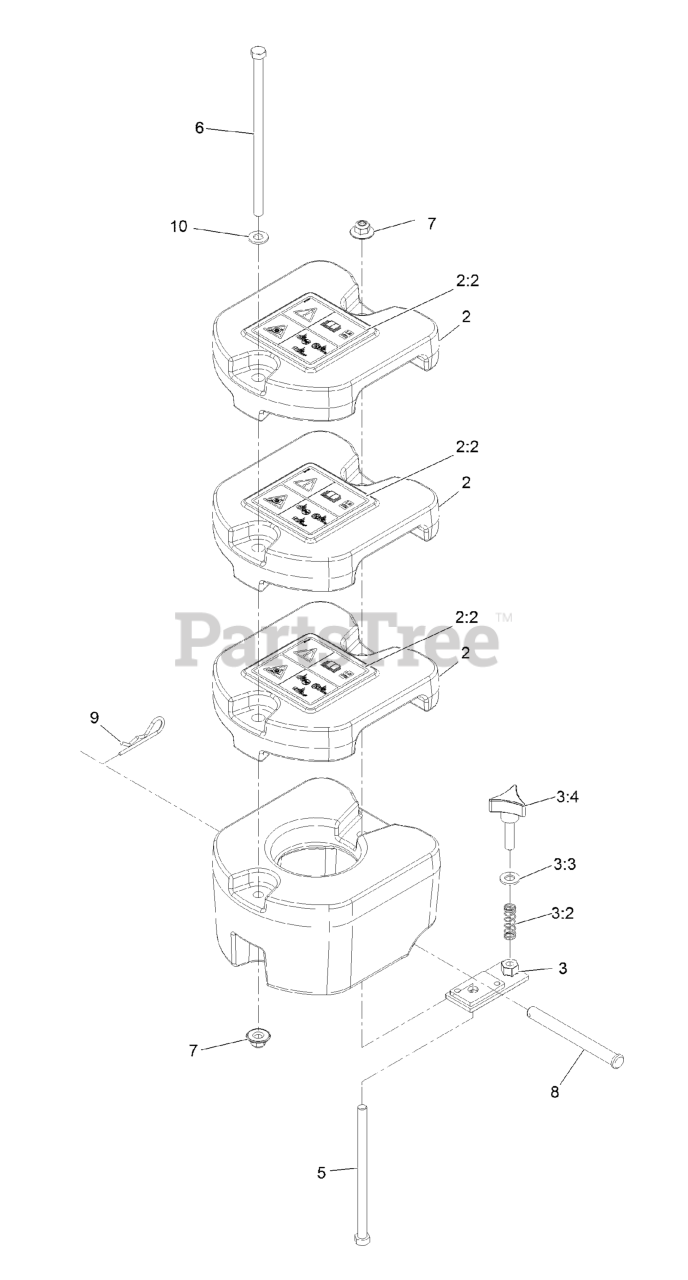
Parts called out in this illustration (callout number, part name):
2	WEIGHT-20LB
2:2	DECAL-WARNING, TRACTION
3	CASTER WEIGHT BRACKET ASM
3:3	WASHER-FLAT
5	SCREW-HH
6	SCREW-HH
7	Nut-Nyloc 3/8-16 Flg
8	PIN-CLEVIS
9	PIN-COTTER
10	WASHER-FLAT
